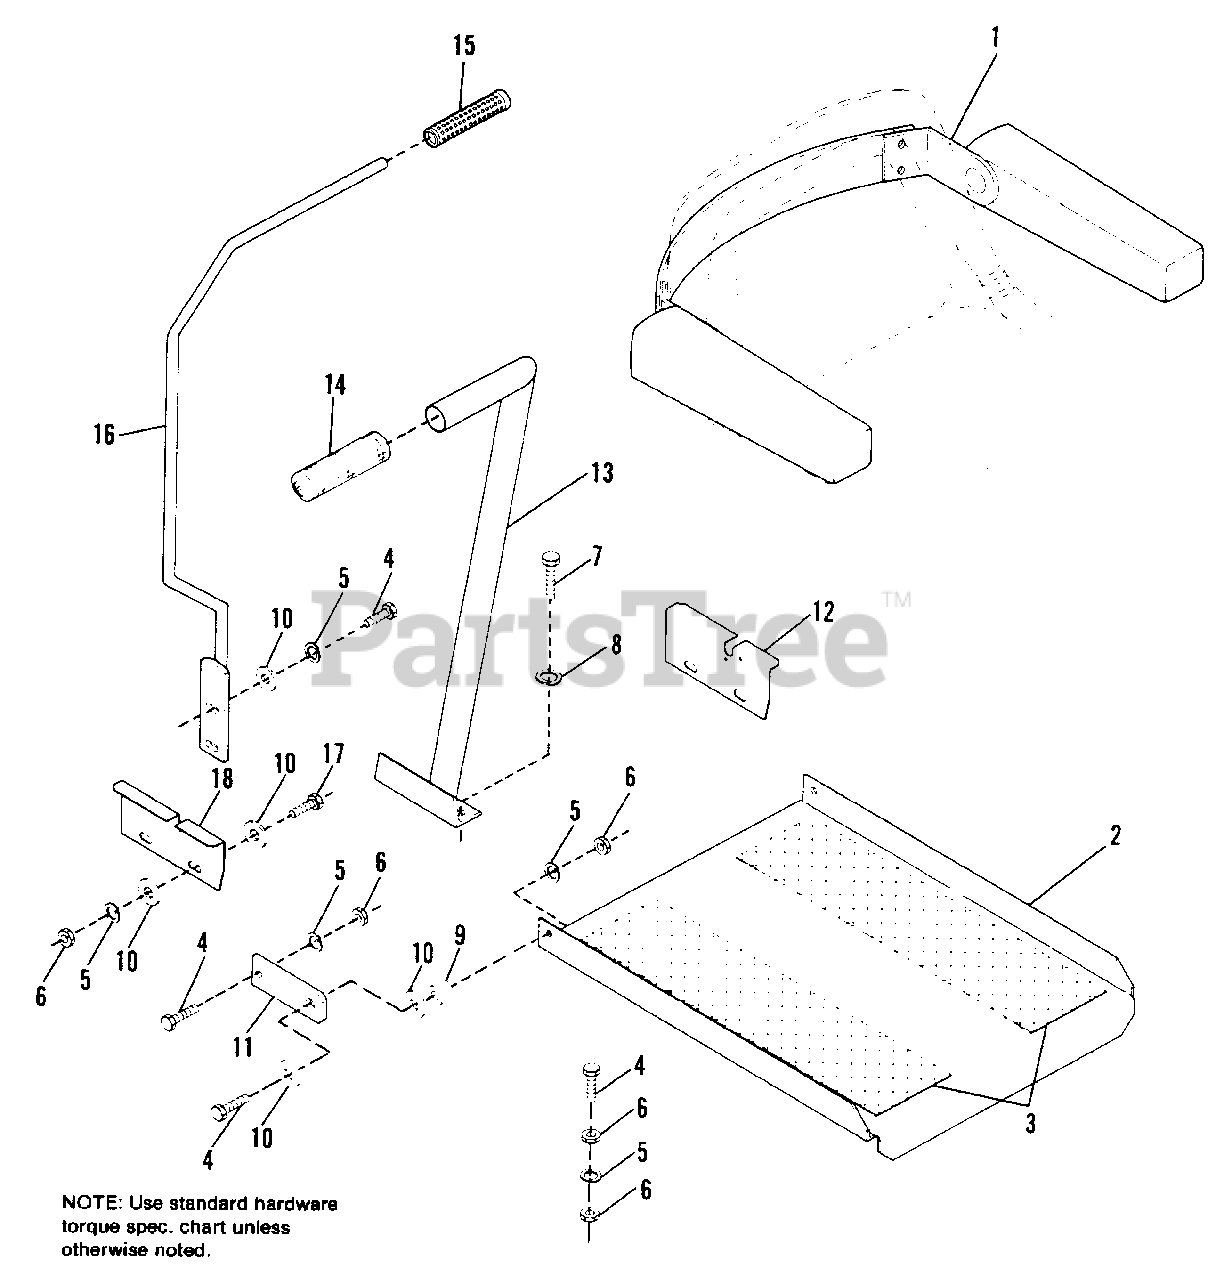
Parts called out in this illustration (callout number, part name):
1	ARM KIT Seat
2	FOOTREST ASSY.
3	PAD, Non-Skid
4	CAPSCREW, Hex, 5/16-18 x 1
5	LOCKWASHER, Spring, 5/16
6	NUT, Hex, 5/16-18
7	CAPSCREW, Hex, 3/18-16 x 1
8	LOCKWASHER, Spring, 3/8
10	WASHER, Plain, 5/16
11	BRACKET, Footrest
12	PLATE, Neutral, L. H.
13	HANDRAIL ASSY.
15	GRIP, Handle
16	HANDLE ASSY.
17	CAPSCREW, Hex, 5/16-18 x 3/4
18	PLATE, Neutral, R.H.
